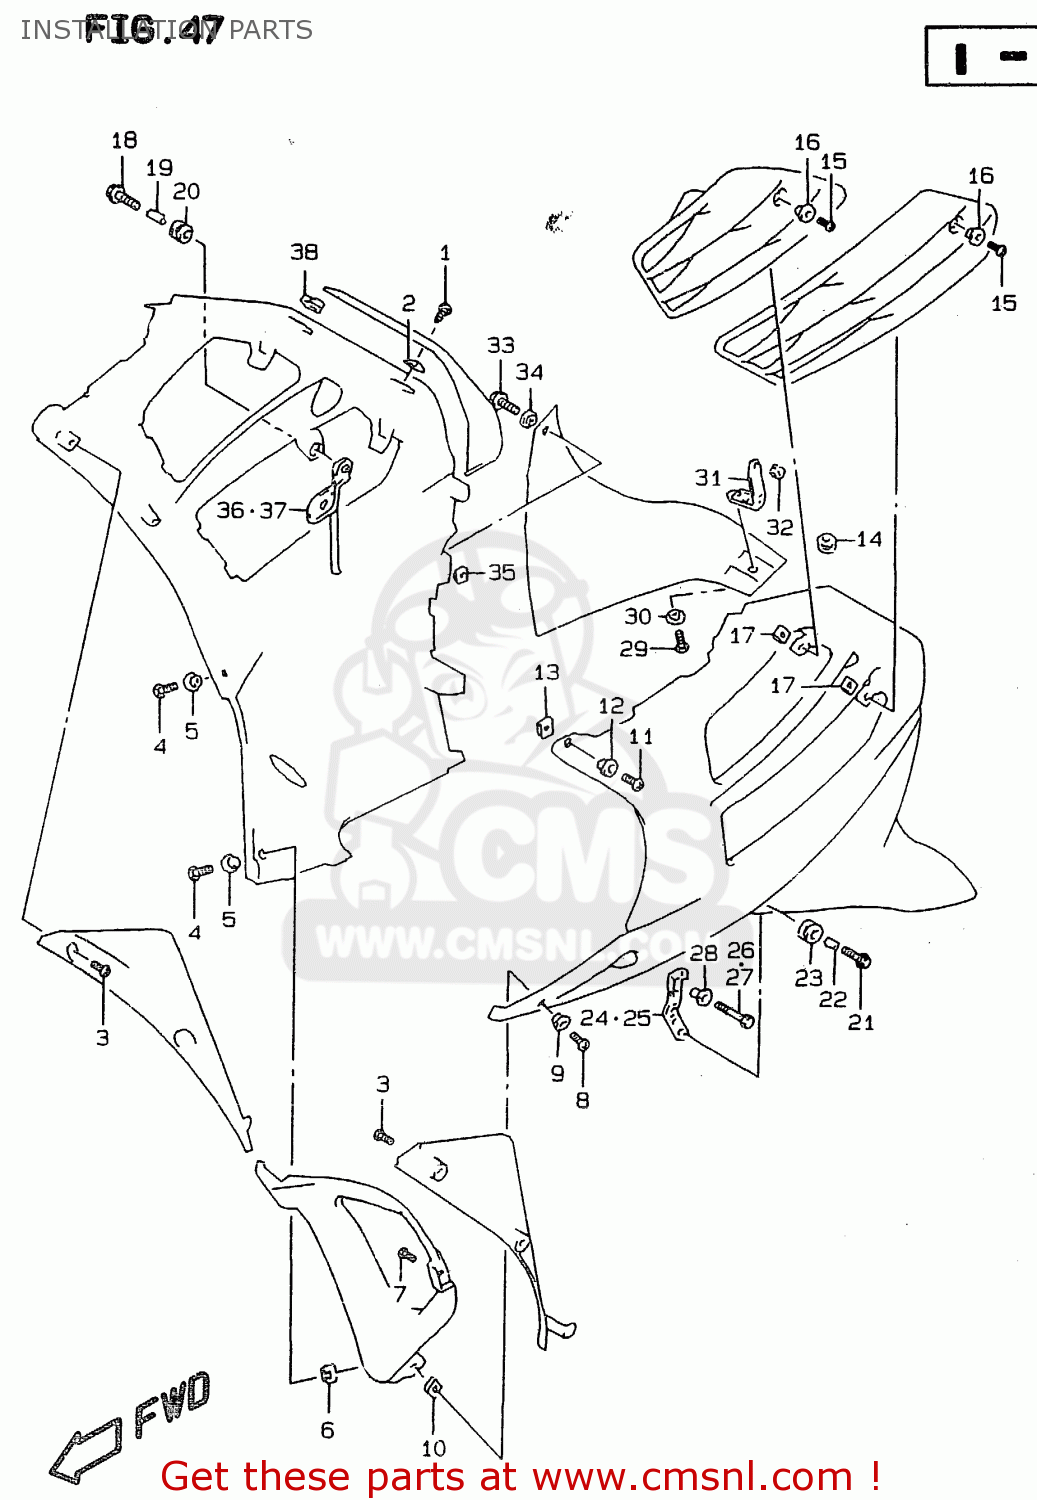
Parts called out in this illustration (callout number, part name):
1	SCREW
2	NUT
3	SCREW 5X10
4	SCREW
5	WASHER(5.2X14X1.5)
6	NUT,HEADLAMP HOUSING,UPPER
7	SCREW 5X10
8	SCREW
9	WASHER(5.2X14X1.5)
10	NUT,HEADLAMP HOUSING,UPPER
11	SCREW
12	WASHER(5.2X14X1.5)
13	NUT,HEADLAMP HOUSING,UPPER
14	CUSHION
15	SCREW
16	WASHER(5.2X14X1.5)
17	NUT,HEADLAMP HOUSING,UPPER
18	BOLT
19	SPACER(6.5X9X10)
20	CUSHION
21	BOLT
22	SPACER(6.5X9X10)
23	CUSHION
24	BRACKET,UNDER COWLING LWR,R
25	BRACKET,UNDER COWLING LWR,L
26	BOLT
27	BOLT
28	SPACER(6.1X10X16)
29	SCREW 5X12
30	WASHER(5.2X14X1.5)
31	BRACKET,RR UNDER COWLING FTG
32	NUT
33	SCREW
34	WASHER(5.2X14X1.5)
35	NUT,HEADLAMP HOUSING,UPPER
36	BRACKET,UNDER COWLING UPR,R
37	BRACKET,UNDER COWLING UPR,L
38	CUSHION,UNDER PANEL
